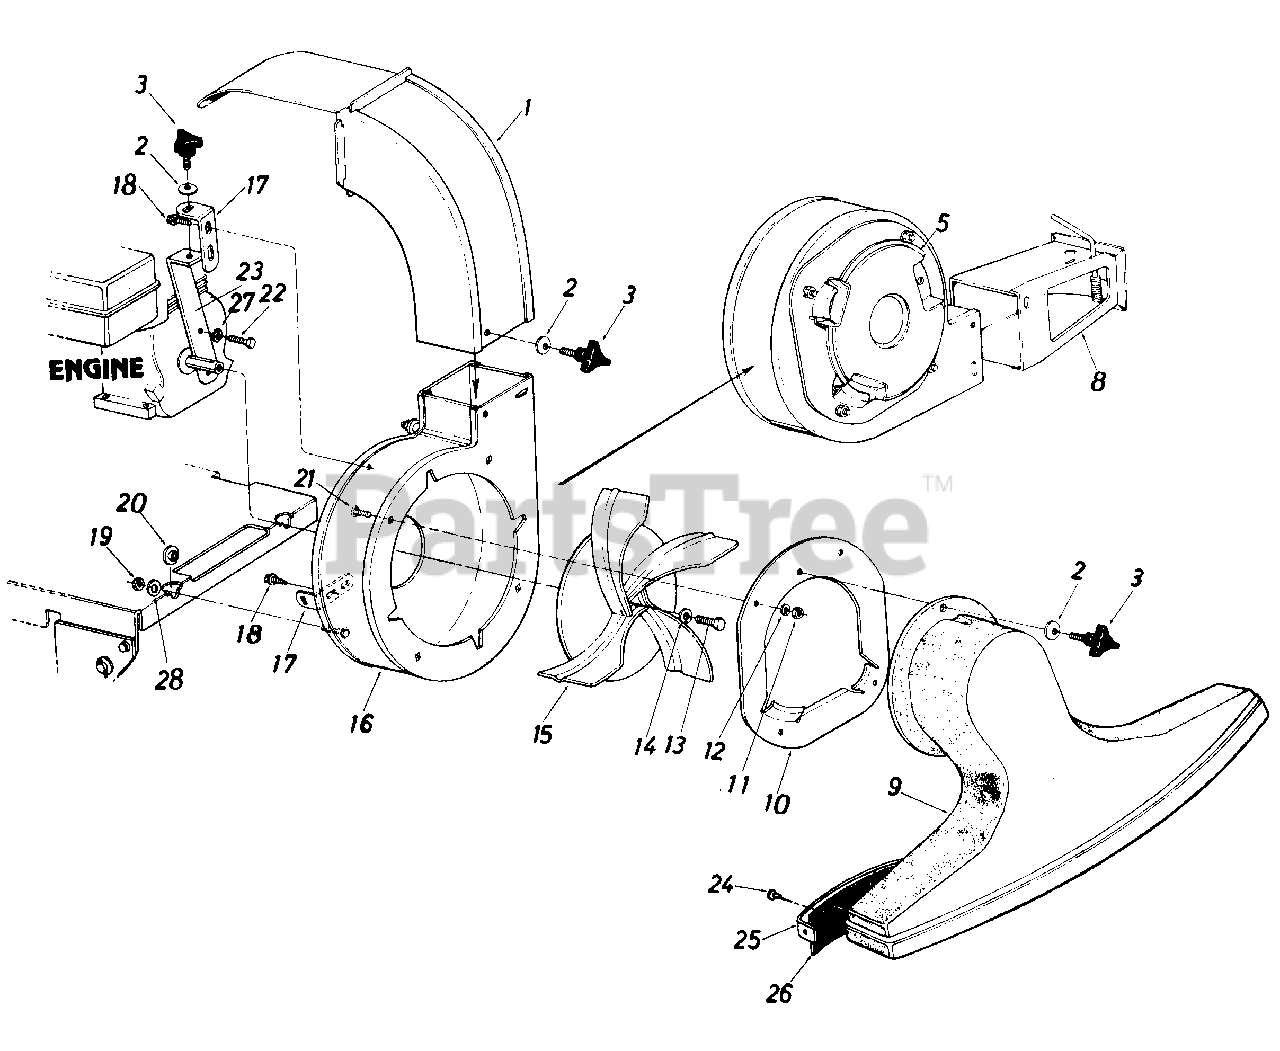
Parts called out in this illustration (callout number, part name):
3	3-Arm Thumb Scr. 5/16-18 x .75" Lg.
5	Blower Guard
10	Nozzle Plate Ass'y.
11	Hex Nut 5/16-18 Thd.
12	L.-Wash. 5/16" I.D.
13	Hex Bolt 3/8-24 x 1.25" Lg.
14	L.-Wash. 3/8" I.D. H.D.
15	Air Vane Plate Ass'y. w/pulley
16	Blower Housing Complete
19	Hex Cent. L.-Nut 5/16-18 Thd.
20	Shoulder Spacer .50" I.D. x .135
21	Carriage Bolt 5/16-18 x .62" Lg.
22	Hex Locking Bolt 5/16-24 x .62" Lg.
27	L.-Wash. 5/16" I.D.
28	Flat Wash..41 I.D. x 1.0 O.D.
